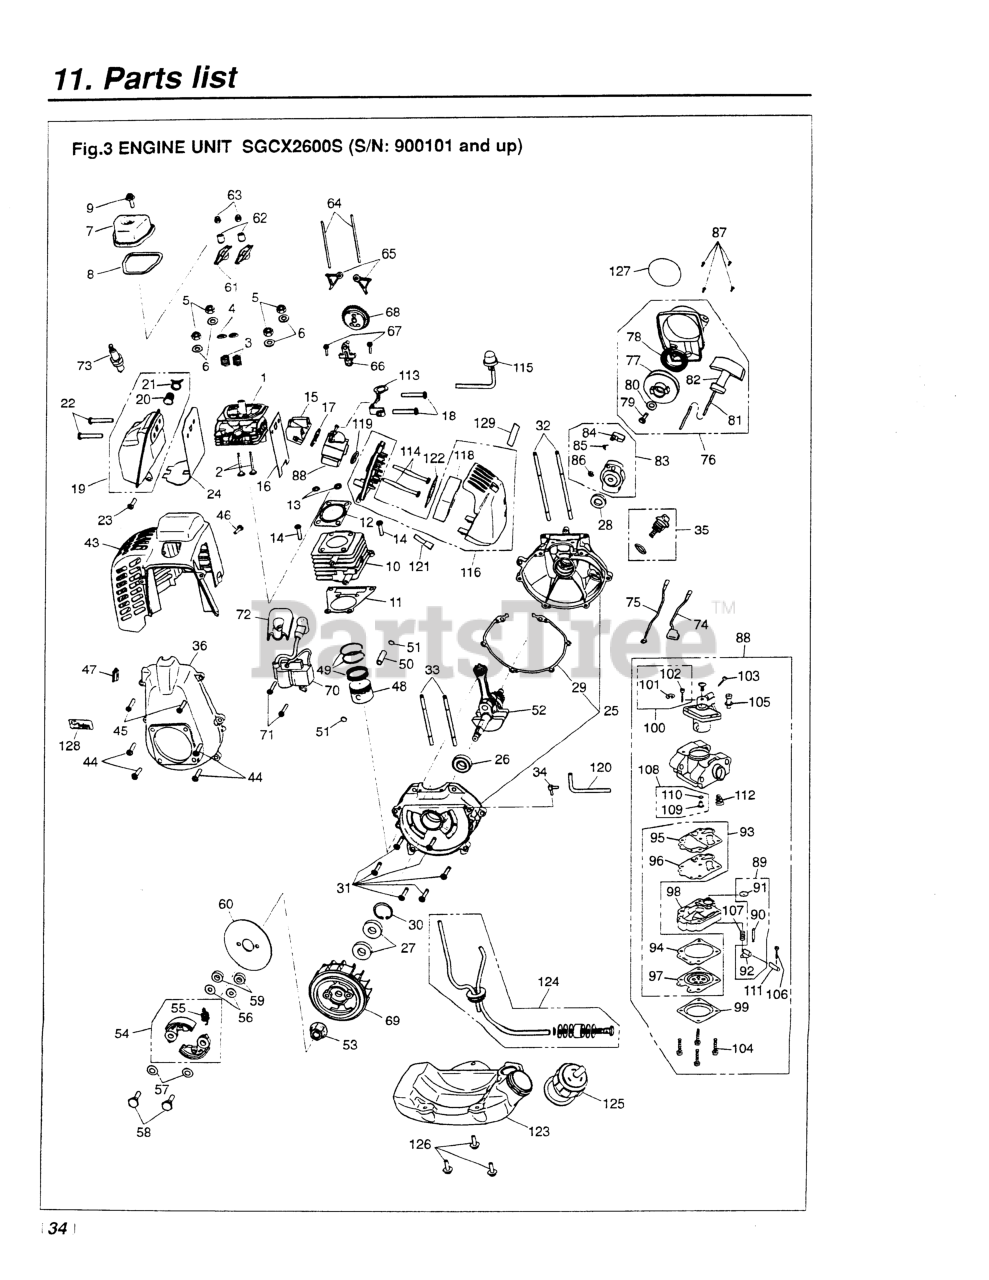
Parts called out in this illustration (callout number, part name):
1	182306 (REPLACES 2062-95110)
2	VALVE (RPLS 2062-11510)
3	SPRING, VALVE (RPLS 2062-11520
4	RETAINER (RPLS 2063-11530)
5	NUT (RPLS 2062-11310)
6	WASHER (RPLS 2062-11320)
7	COVER, VALVE (RPLS 2062-11410)
8	GASKET (RPLS 2062-11420)
9	SCREW (RPLS 2062-11430)
10	CYLINDER (RPLS 2062-12110)
11	GASKET, BASE (RPLS 2062-12210)
12	GASKET, HEAD (RPLS 2062-12220)
13	O-RING (RPLS 2062-12230)
14	SCREW (RPLS 2062-12240)
15	INSULATOR (RPLS 2062-13160)
16	GASKET (RPLS 2062-13120)
17	GASKET, CARB (RPLS 2062-13130)
18	SCREW (RPLS 2062-15220)
19	MUFFLER ASSY (RPLS 2062-15100)
20	ARRESTER (RPLS 2062-15140)
22	SCREW (RPLS 2062-15220)
23	SCREW (RPLS 2062-15230)
24	GASKET (RPLS 2062-15210)
25	CRANKCASE (RPLS 2062-95120)
26	BEARING (RPLS 2062-21420)
27	SEAL (RPLS 2062-21220)
28	SEAL (RPLS 2062-21210)
29	GASKET, BASE (RPLS 2062-21140)
30	RING, SNAP (RPLS 2062-21520)
31	SCREW (RPLS 5850-13210)
32	STUD (RPLS 2062-21160)
33	STUD (RPLS 2062-21170)
34	ELBOW (RPLS 2062-21620)
35	PLUG & 0-RING(RPLS 2062-95130)
36	COVER, FAN
43	COVER, ENGINE (RPLS 2063-32110
44	SCREW (RPLS 2062-12240)
45	SCREW (RPLS 5850-32170)
46	SCREW (RPLS 2062-32140)
47	GROMMET (RPLS 1852-72121)
48	PISTON (RPLS 2063-41110)
49	RING (RPLS 2063-95140)
50	PIN, PISTON (RPLS 2062-41310)
51	BUTTON (RPLS 2062-41320)
52	SHAFT & GEAR (RPLS 2063-45000)
53	NUT (REPLACES 1650-43230)
54	SHOE, CLUTCH (RPLS.2063-51100)
55	SPRING
56	WASHER (REPLACES 1140-51230)
57	WASHER, SPRING (RPL 1970-51241
58	SCREW (REPLACES 2063-51250)
59	SPACER (RPLS 2063-51260)
60	DISK (RPLS 2063-51310)
61	ARM, ROCKER (RPLS 2062-61160)
62	PIVOT (RPLS 2062-61170)
64	ROD, PUSH (RPLS 2062-61210)
65	FOLLOWER, CAM (RPLS 2062-61310
66	BRACKET, CAM (RPLS 2062-61400)
67	SCREW (RPLS 2062-61610)
68	GEAR,CAM (RPLS 2062-61500)
69	ROTOR (RPLS 2063-71110)
70	COIL (RPLS 2062-71200)
71	SCREW, COIL (RPLS 2062-71310)
72	CAP, COVER (RPLS 2063-72140)
74	CORD (A)
75	CORD (B)
76	RECOIL (RPLS 2062-95150)
77	REEL (RPLS 5850-75120)
78	SPRING (RPLS 5850-75130)
79	SCREW (RPLS 5850-75140)
80	WASHER (REPLACES 1400-86280)
81	ROPE (RPLS 5850-75150)
82	KNOB (RPLS 5850-75160)
83	PULLEY ASSY
84	RATCHET (RPLS 5850-75220)
85	SPRING (RPLS 5850-75230)
86	RING, SNAP (RPLS 0308-00040)
87	SCREW (RPLS 2062-75310)
88	CARBURETOR (RPLS 2062-81000)
90	VALVE, INLET
91	SCREEN
92	LEVER
93	KIT, GASKET (D11-WYL)
94	GASKET
95	GASKET, PUMP
96	DIAPHRAGM, PUMP
97	DIAPHRAGM
98	BODY ASSEMBLY, PUMP
99	COVER, DIAPHRAGM
100	SWIVEL - A
101	RING, SPRING RETAINING
102	SWIVEL
103	SCREW, IDLE ADJUST
104	SCREW, COVER
106	SCREW, METERING LEVER PIN
107	SPRING, METERING LEVER
108	KIT, MAIN JET
109	JET
110	O-RING
111	PIN, METERING LEVER
112	SPRING, DIAPHRAGM PUMP
113	BRACKET (RPLS 2062-83110)
114	SCREW (RPLS 2062-83120)
116	CLEANER (RPLS 2062-82000)
118	ELEMENT (RPLS 2062-82150)
119	RING (RPLS 5850-83110)
120	HOSE (RPLS 2062-82310)
121	BREATHER ASSY (RPLS 2062-82400
122	SCREEN (SUB 2062-82160)
123	TANK (RPLS 2063-85000/85110)
124	FUEL LINE ASSY.
125	CAP (RPLS 2062-85200)
126	SCREW (RPLS 2062-85510)
129	LABEL, CLEANER (RPL 2062-91180
